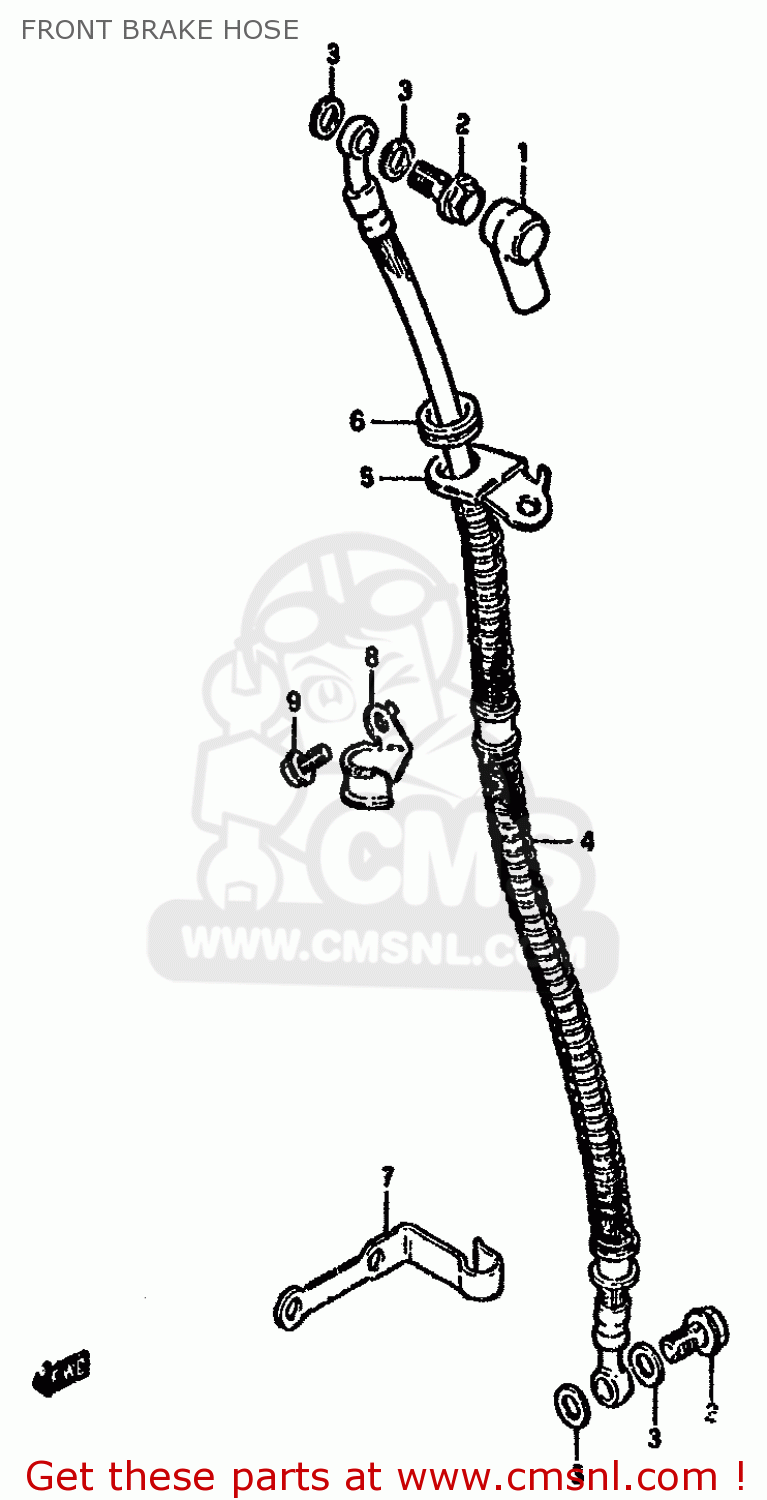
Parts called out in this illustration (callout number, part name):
1	BOOT,MASTER CYLINDER
2	BOLT UNION
3	WASHER(10X15X1.5)
4	HOSE,FR BRAKE
5	GUIDE,BRAKE HOSE
6	GROMMET
7	CLAMP,BRAKE HOSE
8	GUIDE,BRAKE HOSE NO.3
9	BOLT
